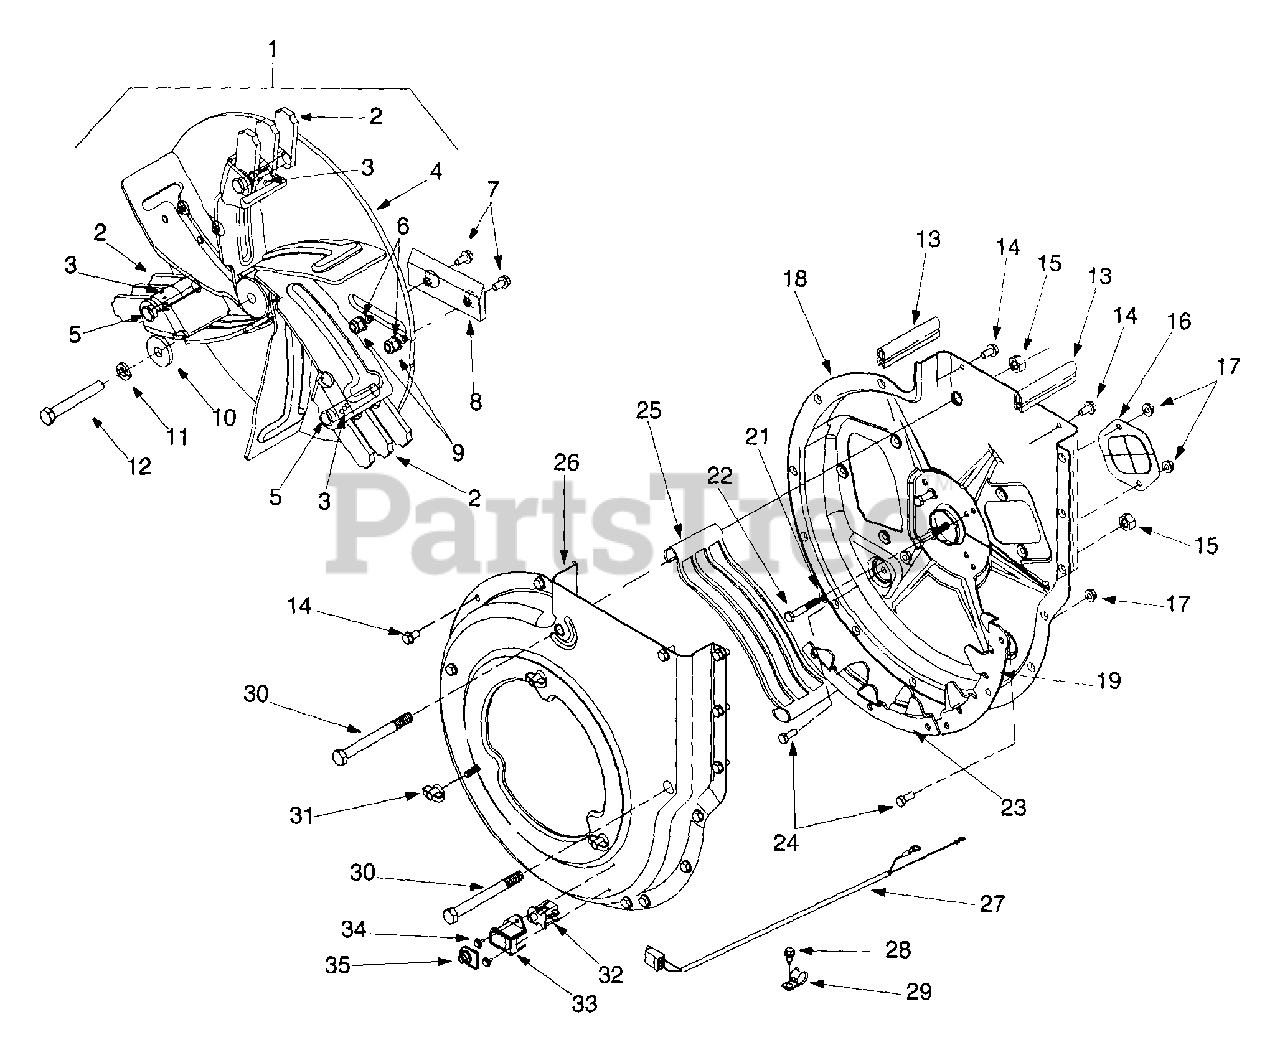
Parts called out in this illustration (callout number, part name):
1	Impeller Ass'y Complete
2	Flail Blade
3	Spiral Pin
4	Impeller Assembly
5	Clevis Pin
6	Lock Washer 5/16
7	Cap Screw 5/16-24 x 1.0
8	Chipper Blade
9	Hex Lock Nut 5/16-24
10	Flat Washer .406 x 1/1/4
11	Lock Washer 3/8
12	Hex Cap Screw 3/8-24 x 2.75
13	Rubber Seal
14	Hex Washer Screw 5/16-18
15	Hex Lock Nut 1/2-13
17	Hex Flange Lock Nut 5/16-18
19	Upper Shredder Blade
21	Lock Washer 5/16
22	Hex Cap Screw 5/16-18 x 2
23	Flail Housing Blade
24	Hex Cap Screw 5/16-18 x .75
25	Discharge Screen
27	Wire Harness
28	Hex Washer Screw 1/4-14
29	Clamp
30	Hex Cap Screw 1/2-13 x 5.0
31	Knob 5/16-18
32	Switch
33	Safety Switch Mounting Cover
34	Hex Washer Screw
35	Switch Cover
